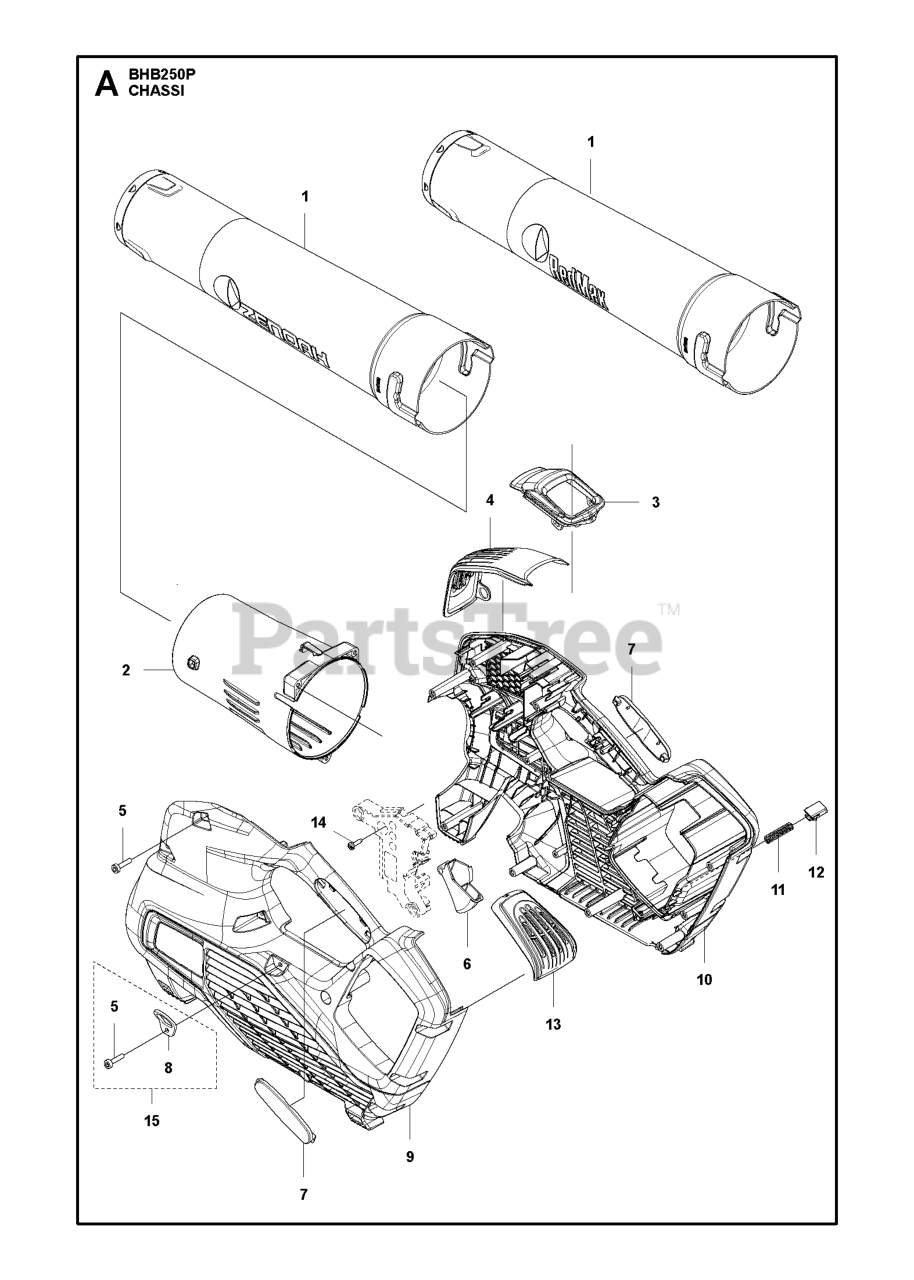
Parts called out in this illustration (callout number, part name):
1	TUBE ASSY NOZZLE REDMAX
2	TUBE FAN SYSTEM BLACK
3	FRAME KEYPAD BLACK
4	COVER FRONT ZENOAH/REDMAX
6	THROTTLE CONTROL BLACK
7	HANDLE INSERT ZENOAH/REDMAX B
11	SPRING PUSH OUT
12	PUSH BUTTON
13	COVER AIR OUTLET ZENOAH/REDMAX
14	SCREW CCRPANT
15	KIT EYELET
